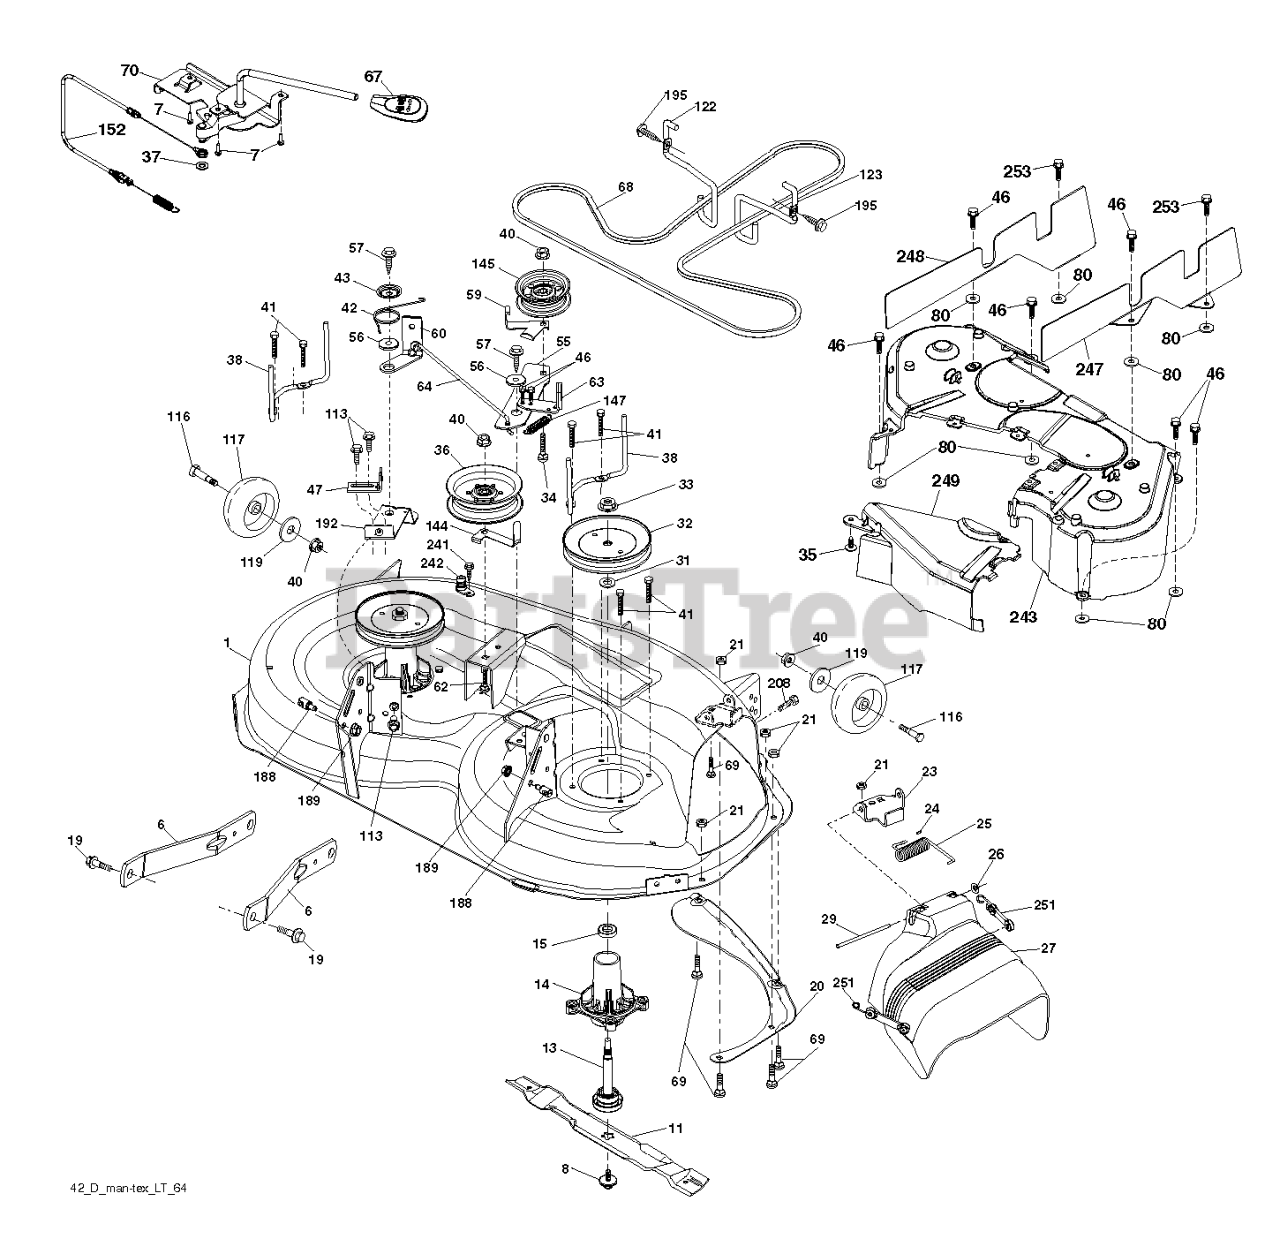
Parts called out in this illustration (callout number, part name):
1	DECK.WELDMNT.42"GREYMS498
6	ARM.SUSPENSION.MOWER.R
7	SCREW.#10 X 0.750.BOS
8	BOLT.WASHER.ASM.7/16-2
11	42" HI-LIFT BLADE
13	SHAFT.ASM.MDRL.N/GREASE.38
14	RP.HOUSING.MANDREL.4PT.
19	BOLT.SHOULDER
20	BAFFLE.VORTEX
21	LOCKNUT
23	BRKT.DEFLECTOR.38"2005+
24	CAP-SLEEVE LT
25	SPRING.TORSION.DEFLECT
26	NUT PUSH M
27	DEFLECTOR ASM.42"TEX.FRENCH
29	ROD.HINGE
31	WASHER.SPACER.MANDREL
32	PULLEY.MANDREL.5.438.PD
33	NUT.FLANGE.LOCK.TOP
34	BOLT.3/8-16X1.50
35	FASTENER.XMAS.TREE
36	PULLEY.IDLER.2006
37	WASHER
38	KEEPER.BELT.MANDREL.PULLEY
40	NUT LOCK FLG 3/8-16 UNC
41	BOLT.HEX.WASHR.HED.313-18X1.19
42	SPRING.TORSION.BRAKE
43	SRPING.TORSION.RETAINE
46	SCREW.1/4-20X5/8
47	BRKT.CLUTCH.CABLE
55	IDLER.ARM.42"
56	SPACER.RETAINER
57	SCREW 3/8-16X1
59	GUARD, BELT
60	ARM BRAKE MOWER
62	BOLT
63	ARM BRAKE MOWER
64	LINKAGE.BRAKE.ASM.ZINC
67	HANDLE.CLUTCH.CABLE.LT
68	BELT.DECK.DRIVE.42"
69	BOLT
70	CLUTCH.ASM.MANUAL.LT.PRED
80	PALNUT 1/4
113	BOLT.5/16HEX.WHS.HD
116	BOLT M
117	WHEEL.GAGE.HALF.SPOKED
119	WASHER.5/16.FLAT.STE.STD.
122	KEEPER BELT ENGINE LH
123	KEEPER BELT RH
144	KEEPER.BELT.MOWER
145	PULLEY.IDLER.48"PRIMARY
147	RETURN SPRING
152	CABLE.MECHANICAL.CLUTCH
188	STUD.FASTNER.W/ANTI-ROTATE
189	NUT LOCK HEX FLANGE 5/16-18
192	BRKT.BRAKE.STAND.LH.
195	SCREW, 3/8-16X3/4
208	SCREW 3/8-16X1/2
241	SCREW.TT.#10-32X.5.3/8.FLANGE
242	PORT.WASHOUT
243	COVER DECK
247	SHIELD DECK RIGHT
248	SHIELD DECK LEFT
249	COVER CABLE CLUTCH
251	ELASTIC STRAP KIT
253	SCREW
